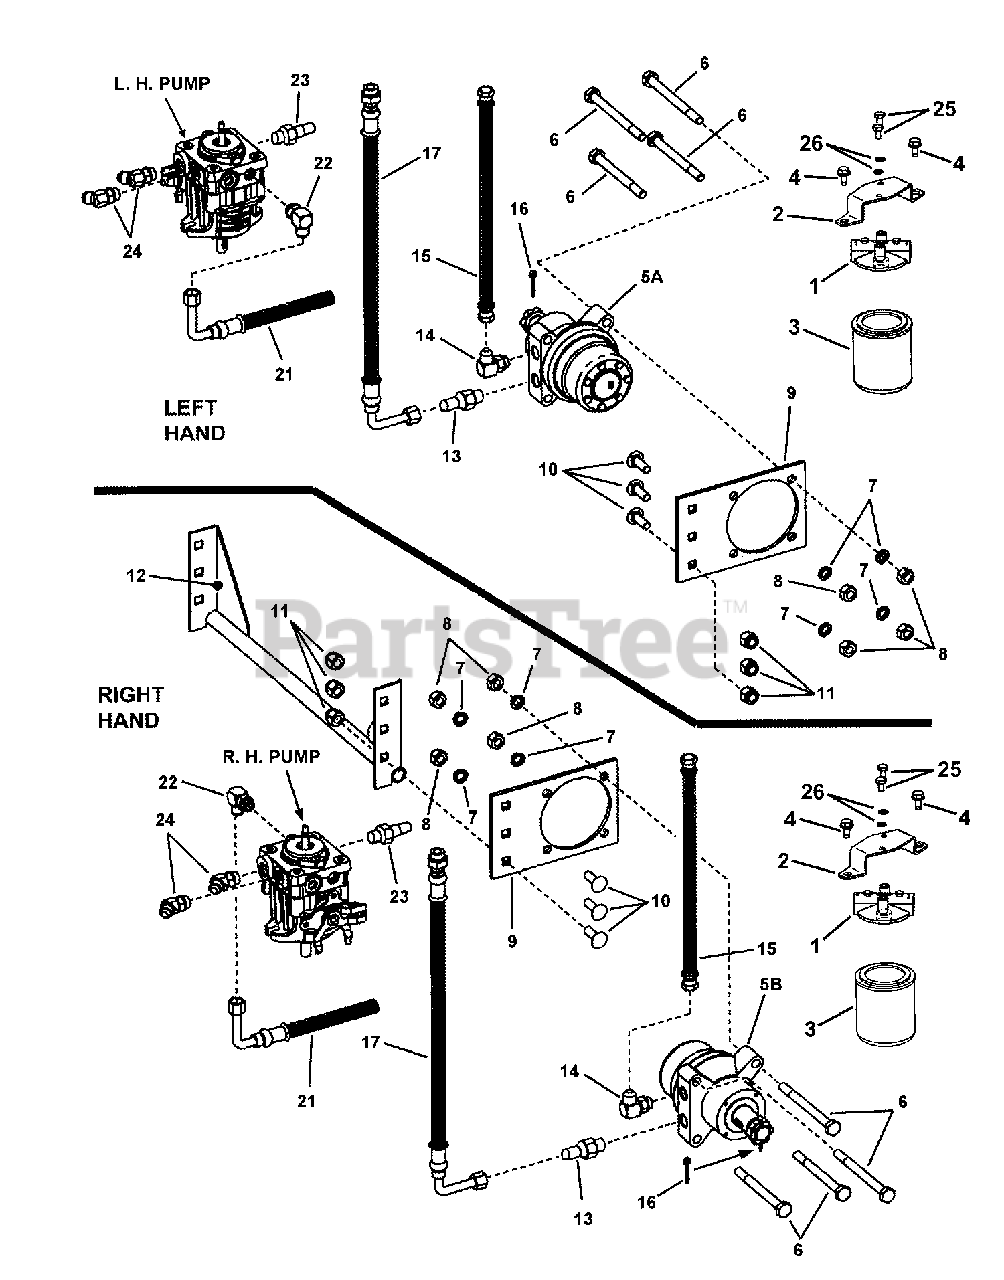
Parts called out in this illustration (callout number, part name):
1	FILTER HEAD
2	BRACKET, Filter
3	FILTER, OIL
4	SCREW, 5/16-18 x 5/8" Hex Washer Self-Tap
5A	MOTOR, Hydraulic, Left Hand
5B	MOTOR, Hydraulic, Right Hand
6	BOLT, 1/2-13 x 6" Hex Head Cap GR 5
7	WASHER, 1/2" Split Lock
8	NUT, 1/2-13 HEX
9	MOUNTING PLATE, Hydro Motor
10	BOLT, 1/2-13 x 1-1/2" Square Neck Carriage, GR 5
11	NUT, 1/2-13 Hex Nyloc
12	WELDMENT, Rear Crossbrace
13	CONNECTOR, Straight Hydraulic (Parker # 8-10 F5OLO-S)
14	CONNECTOR, 90 Degree Hydraulic (Parker # 8-10 C5OLO-S)
15	HOSE, 13-3/4" Hydraulic (Parker # F436BKJCJC080808-13-75)
16	COTTER PIN, 1/8 x 1-1/2"
17	HOSE, 17-1/2" Hydraulic (Parker # F436BKJCJ5080808-17.5)
21	HOSE, 6-1/2" (Parker # R836BKJ9NR080008-6.5)
22	CONNECTOR, 90 Degree Hydraulic (Parker # 8-6 C5OLO-S)
23	CONNECTOR, Straight Hydraulic (Parker # 8-6 F5OLO-S)
24	CONNECTOR, 45 Degree Hydraulic (Parker # V5OLO-S)
25	SCREW, 1/4-20 x 1/2" Hex Head Cap, GR 5
26	WASHER, 1/4" Split Lock
